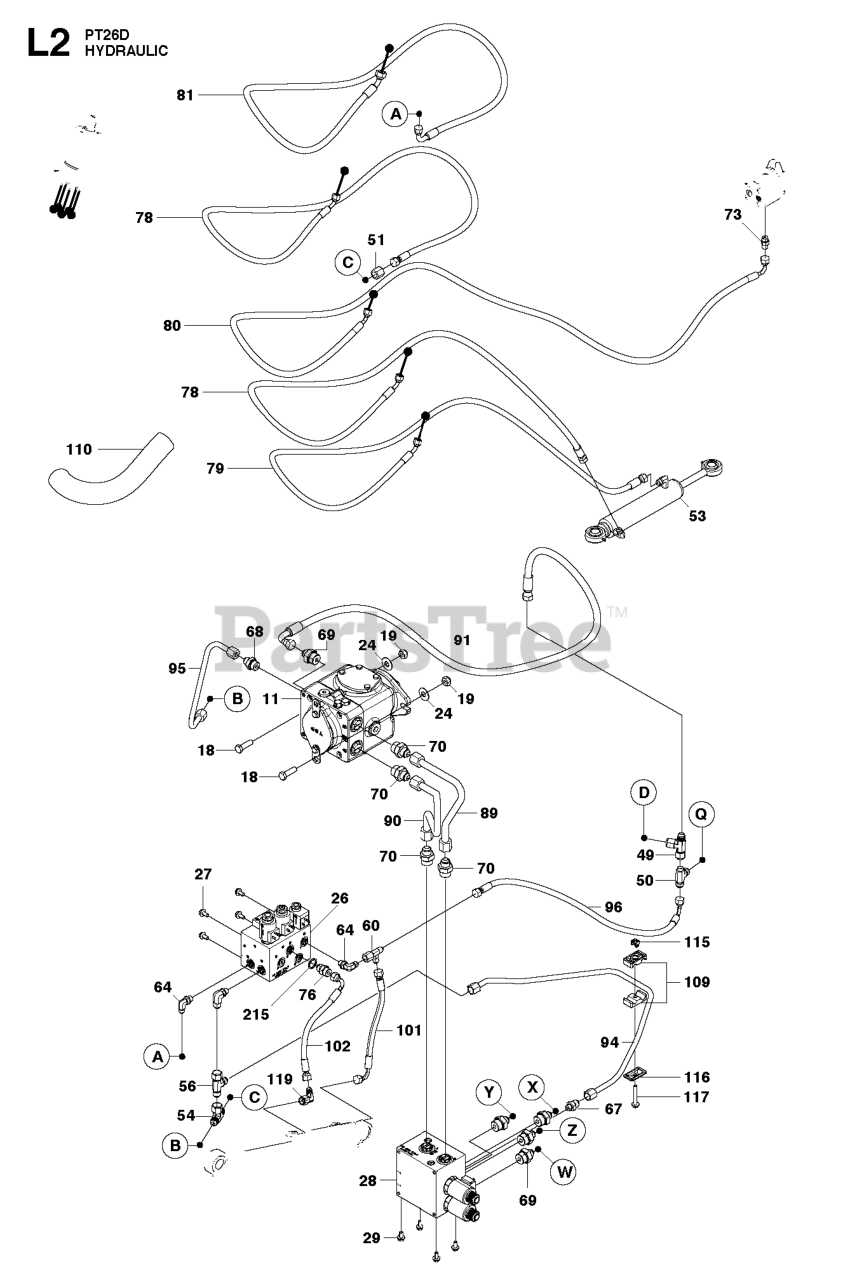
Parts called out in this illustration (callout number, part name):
53	HYDRAULIC CYLINDER
119	PIPE FITTING
215	O-RING 12X2 NITRIL
